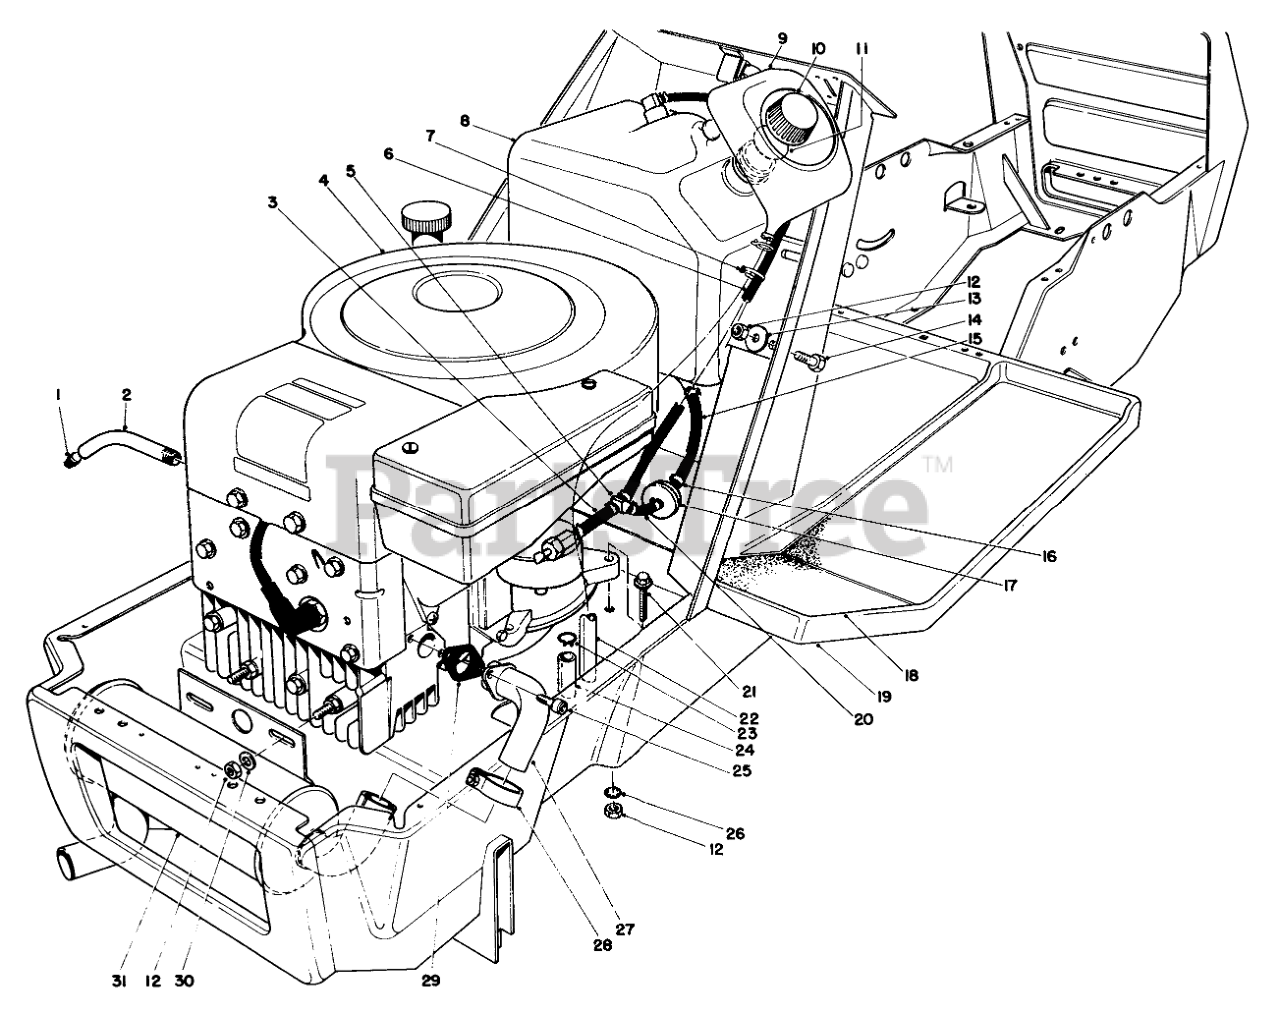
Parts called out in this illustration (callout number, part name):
1	PLUG-PIPE, SQH
2	OIL DRAIN TUBE
3	GAS HOSE
4	Engine
5	Fitting-Barbed Y
6	Hose-Gas Return
7	TIE-CABLE
8	Gas Tank Assy. (Incl. Ref. #9)
9	Funnel-Overflow
10	Gas Cap Assy. (Incl. Ref. #11)
11	Gasket Gas Cap
12	NUT-LOCK, CONE
13	WASHER
14	SCREW-HH
15	HOSE-FUEL
16	FUEL HOSE CLAMP
17	Nut
18	LH FOOT TREAD
19	Frame
20	GAS HOSE
21	SCREW-HH
22	FUNNEL HOSE
23	HOSE CLAMP
24	CARB DRAIN HOSE
25	SCREW-HSH
26	WASHER-LOCK, INTERNAL
27	10 HP EXHAUST PIPE WA
28	MUFFLER CLAMP
29	Exhaust Gasket
30	WASHER-PLAIN
31	EXHAUST MUFFLER 10 HP
